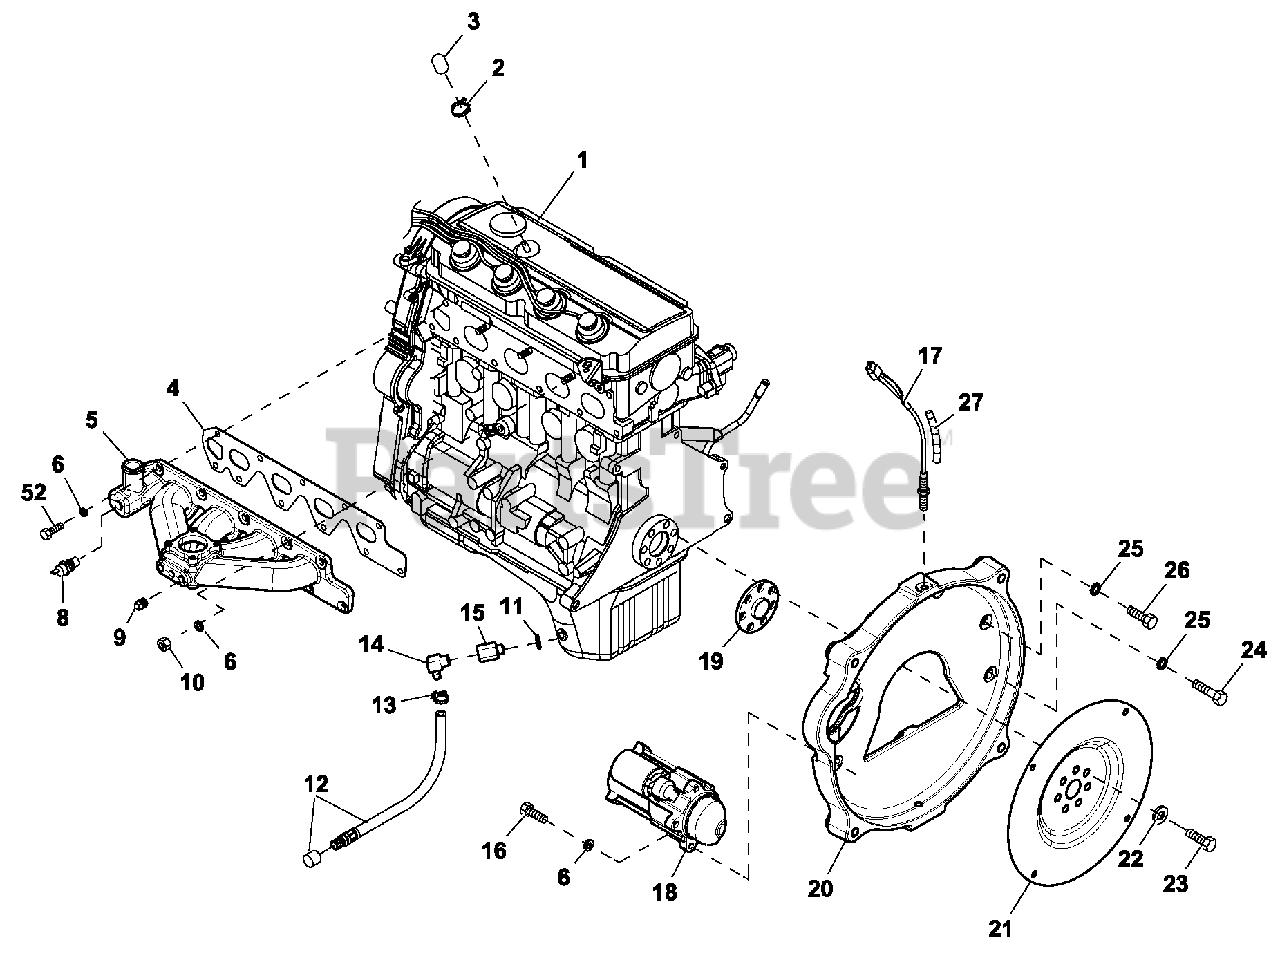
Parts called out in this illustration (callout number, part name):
1	ENGINE 2 .4LG2 CERTIFIED
2	CLAMP HOSE #6 .43-.78
3	CAP ANTIFREEZE RU BBER 9.5DIA
4	GASKET INTAKE MANIFOLD G2
5	MANIFOLD INTAKE (MACHINED)
6	WASHER LOCK M8-5/16
8	TEMPERAT U RE SENDER, DELPHI
9	PL U G STD PIPE 1/4 STEEL SQ HD
10	N U T HEX M8-1.25 G8 CLEAR ZINC
11	WASHER NYLON .565
12	HOSE DRAIN ASSY 28"
13	CLAMP HOSE .38- 87
14	BARBED EL 90 3/8NPT X 3/8 VS
15	ADAPTER M14-1.50X 3/8 NPT
16	SCREW SHC M8-1.25 X 30 C12.9
17	MAGNETIC PICKUP
18	MOTOR STARTER
19	SPACER 2.4L G2 FLEX PLATE
20	ADAPTER ENGINE
21	FLEX PLATE 2 POLE 2.4L G2
22	WASHER FLAT .531 ID X 1.062 OD
23	SCREW HHC M12-1.25X 20 C10.9
24	SCREW HHC M 1 0-1 .2 5X4 5 G8.8
24	SCREW HHC M 1 0-1 .2 5X 3 0 G8.8
25	WASHER SHAKEPROOF EXT 7/16 STL
27	CONDUIT FLEX .25"ID
52	SCREW HHC M8-1.25X 25 G10.9
